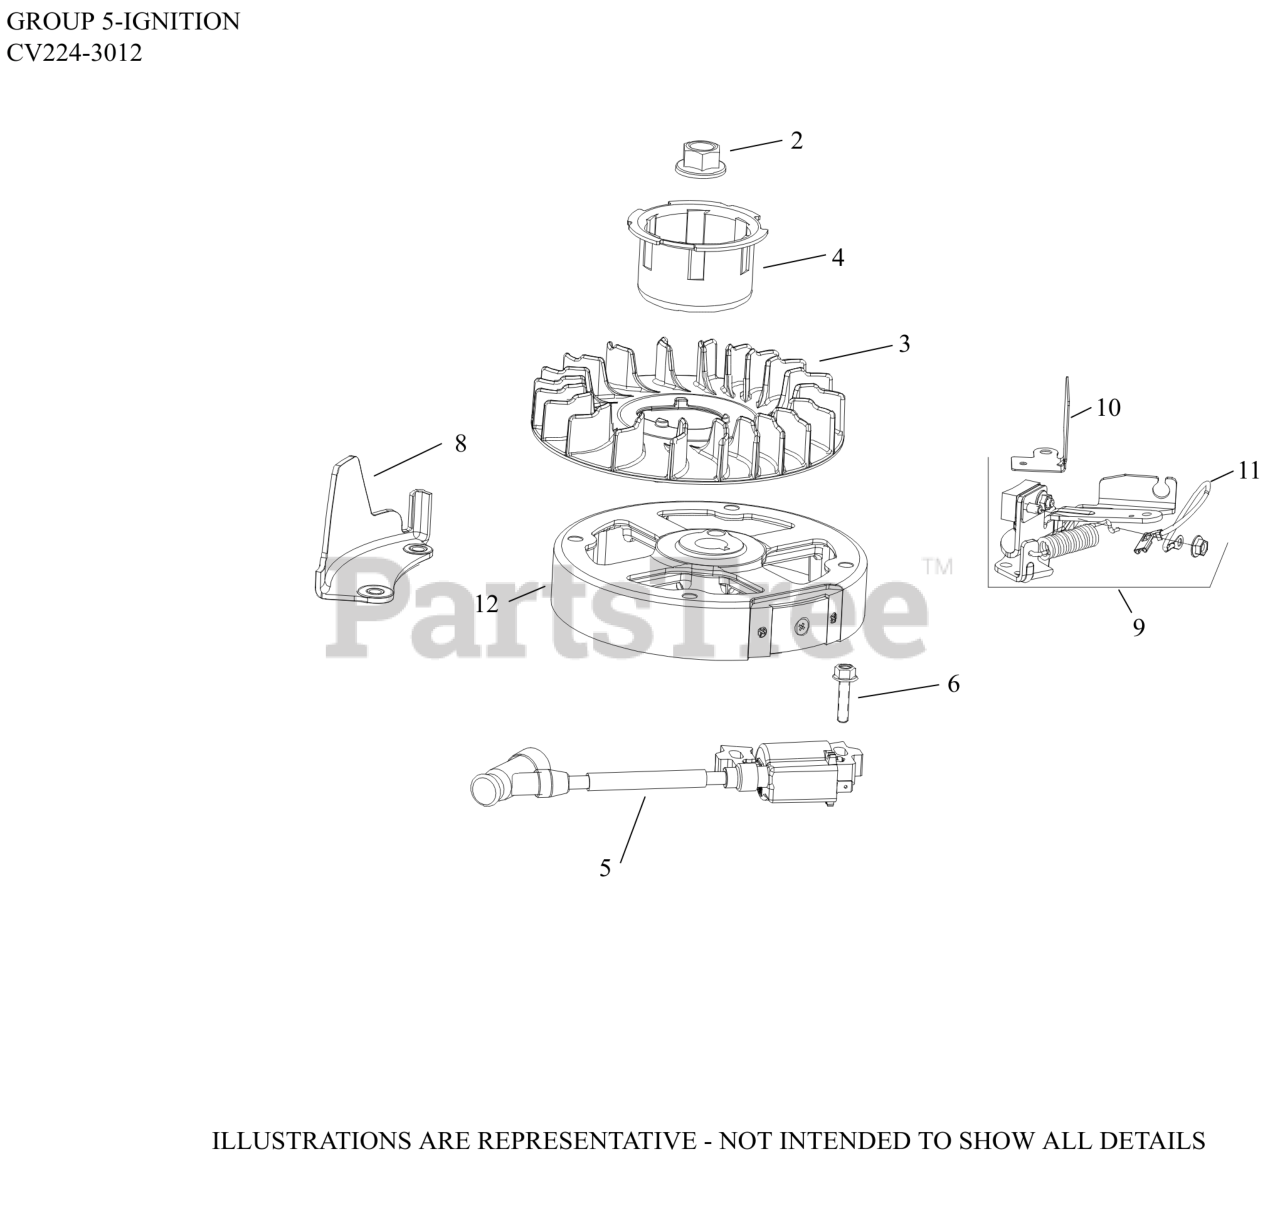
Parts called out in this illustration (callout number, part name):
2	NUT, FLYWHEEL (W/SERRATIONS)
3	FAN, FLYWHEEL
4	CUP, STARTER DRIVE
5	MODULE IGN (#1458416S)
6	SCREW, M6 X 25-(#25086436S)
8	GUARD, FINGER
9	BRAKE ASSEMBLY
10	GUARD, BRAKE - USE 14 314 30-S
11	LEAD, KILL (BRAKE TO IGN. MODULE)
12	FLYWHEEL ASSEMBLY
